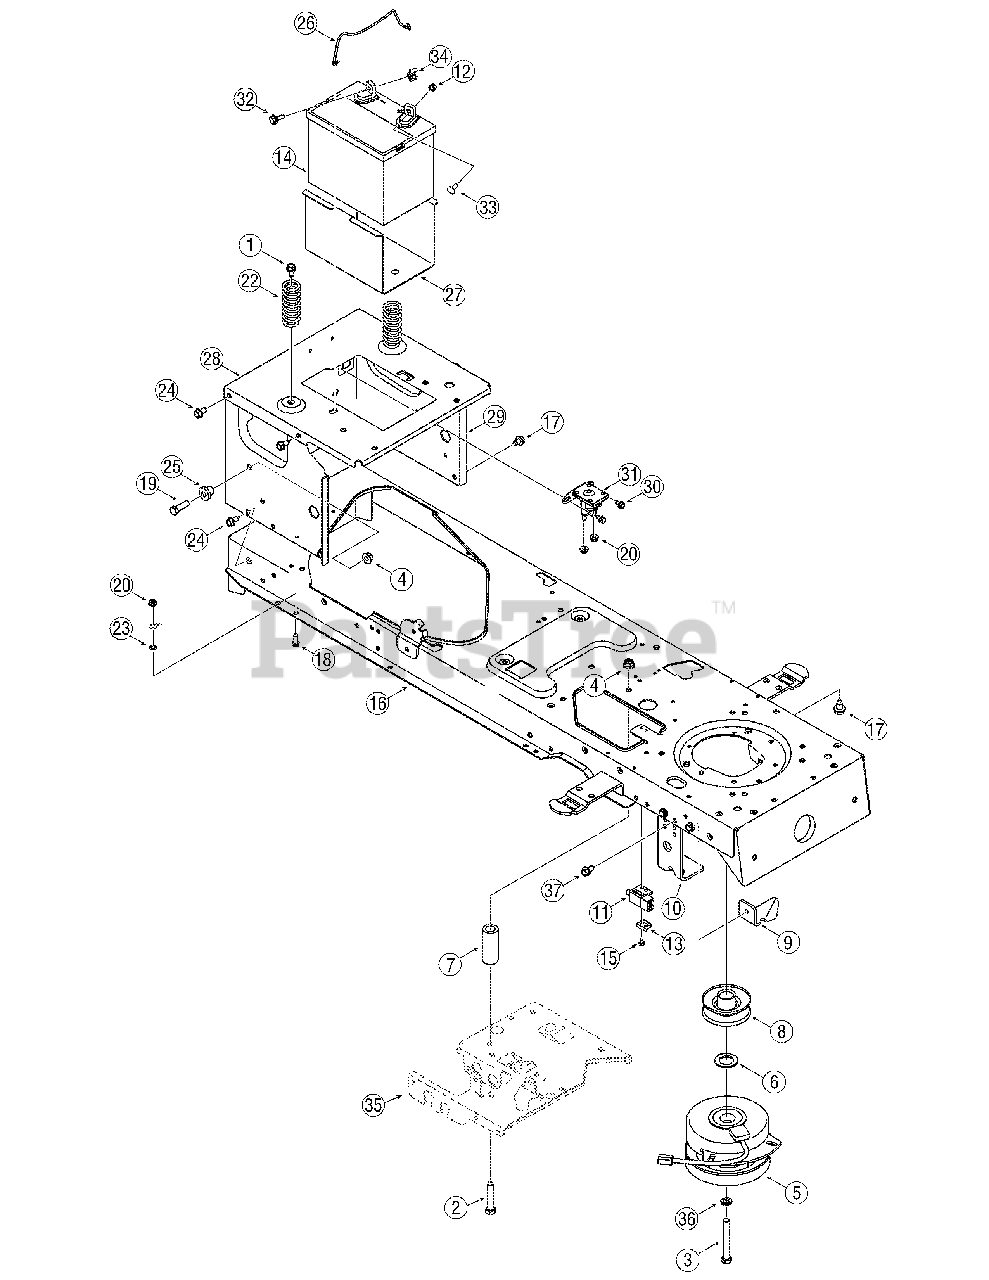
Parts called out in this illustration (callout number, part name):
1	Screw, 5/16-18 x 0.75
2	Screw, 3/8-16, 2.25, Gr5
3	Screw, 7/16-20, 3.50, Gr5, Lock
4	Nut, Flange Lock, 3/8-16
5	PTO Clutch, Electric
6	Washer, Flat, 1.031 x 1.620 x.095
7	Spacer,.385 ID x.635 OD x 1.54
8	Pulley, Engine, 3.56 Diameter
10	Deck Bracket, Up-Stop
11	Switch
12	Nut, Sems, 1/4-20
13	Switch Plate
14	Battery, 235 CCA
15	AB Screw, #10-16 x.500
18	Screw, 1/4-20, 0.750
19	Screw, 3/8-16, 1.25, Gr5
20	Nut, Flange Lock, 1/4-20
22	Spring, Compress., 1.28 x 3.125
23	Washer, Lock, 1/4, External
24	Screw, 5/16-18, 0.625
25	Spacer, Shoulder,.38 x 1.0 x.70
26	Hold Rod, Battery
31	Solenoid, 12V, 100 Amp
32	Screw, Shoulder,.250 x.15, 1/4-20
33	Hex Flange Bolt, 1/4-20,.75
34	Nut, Wing, 1/4-20
36	Lock Washer, 7/16
37	Screw, 5/16-12 x .750
